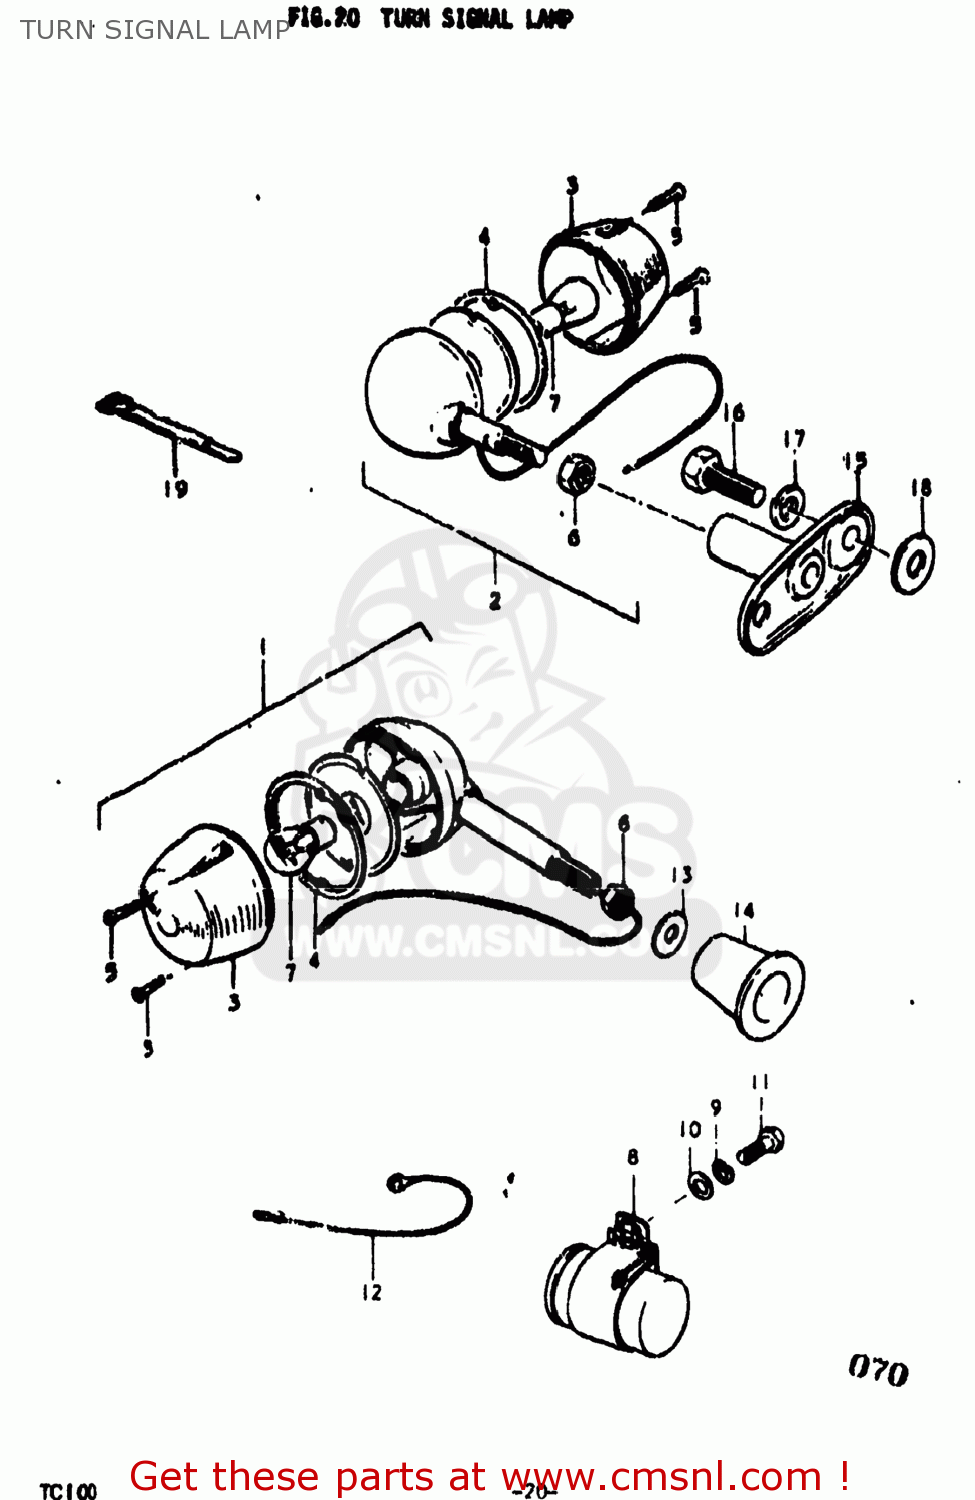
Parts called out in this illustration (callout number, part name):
1	LAMP ASSEMBLY,FRONT TURN SIGNAL
2	LAMP ASSEMBLY,FRONT TURN SIGNAL
3	LAMP ASSEMBLY,REAR TURN SIGNAL
4	LAMP ASSEMBLY,REAR TURN SIGNAL
5	LENS
6	GASKET (NAS)
7	SCREW
8	GASKET (NAS)
9	NUT
10	BULB(6V17W,STANLEY,A4513A)
11	CUSHION
12	SPACER,RR TURNSIGNAL LAMP
13	WASHER (10.5X30X2.3)
14	LOCK WASHER
15	NUT
16	LEAD WIRE,EARTH
